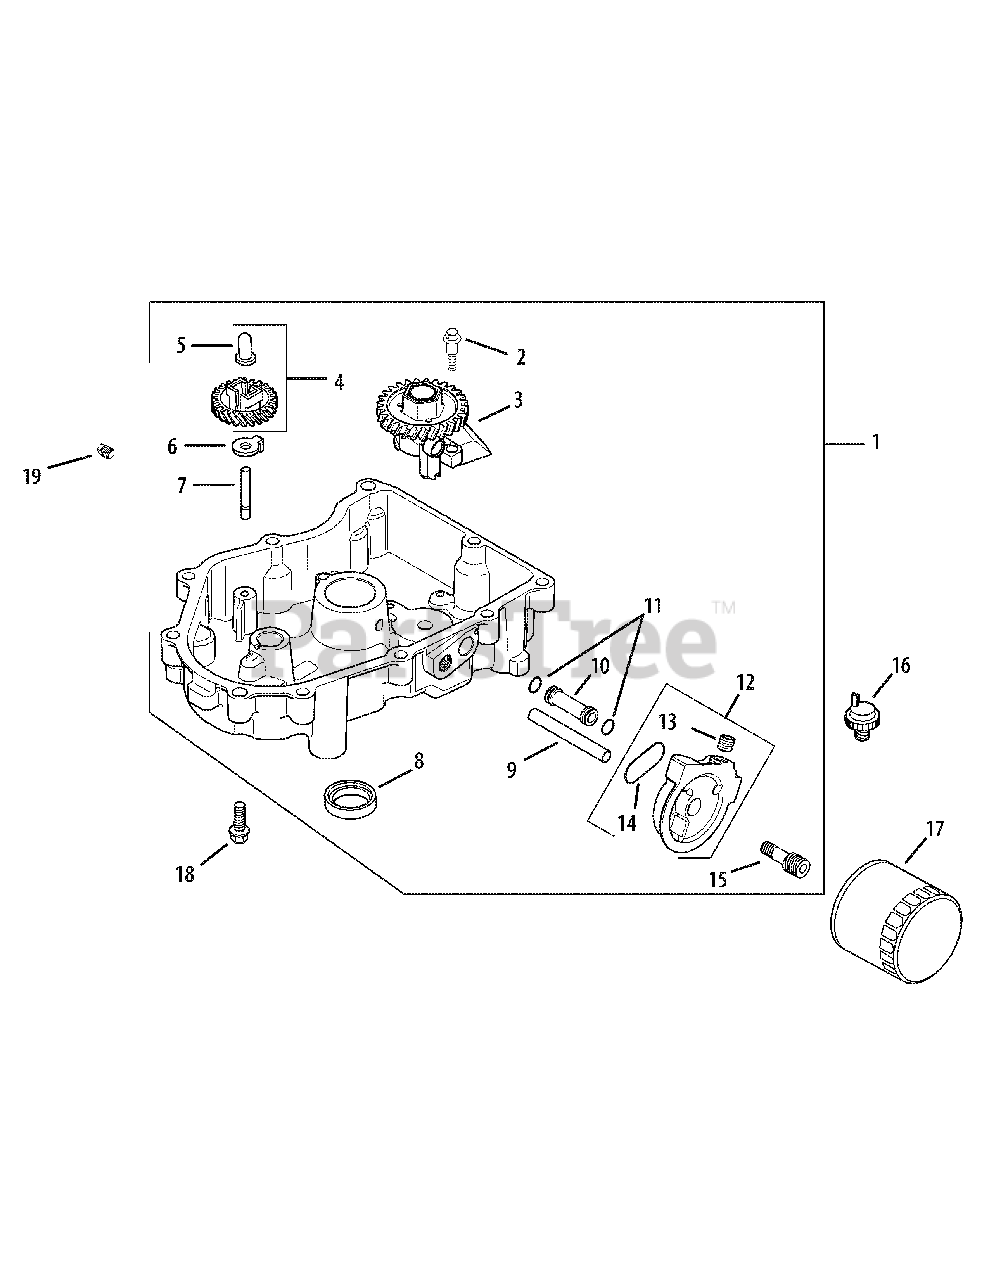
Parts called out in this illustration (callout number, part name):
1	Pan assembly, oil
2	Screw, hex. flange thread forming shoulder
3	Oil pump assembly
4	Kit, governor gear w/pin
5	Pin, governor regulating
7	Shaft, governor gear
8	Seal, oil (PTO end)
9	Tube, oil feed - filter to oil pan
10	Tube, oil feed - oil pan to filter
12	Adapter, oil filter
13	Plug, hex. ctsk. 1/8"
14	O-Ring, oil filter adapter
15	Nipple, oil filter
16	Switch, pressure
18	Screw, hex. flange M8x1.25x45
19	Plug, sq. hd. solid 3/8"
